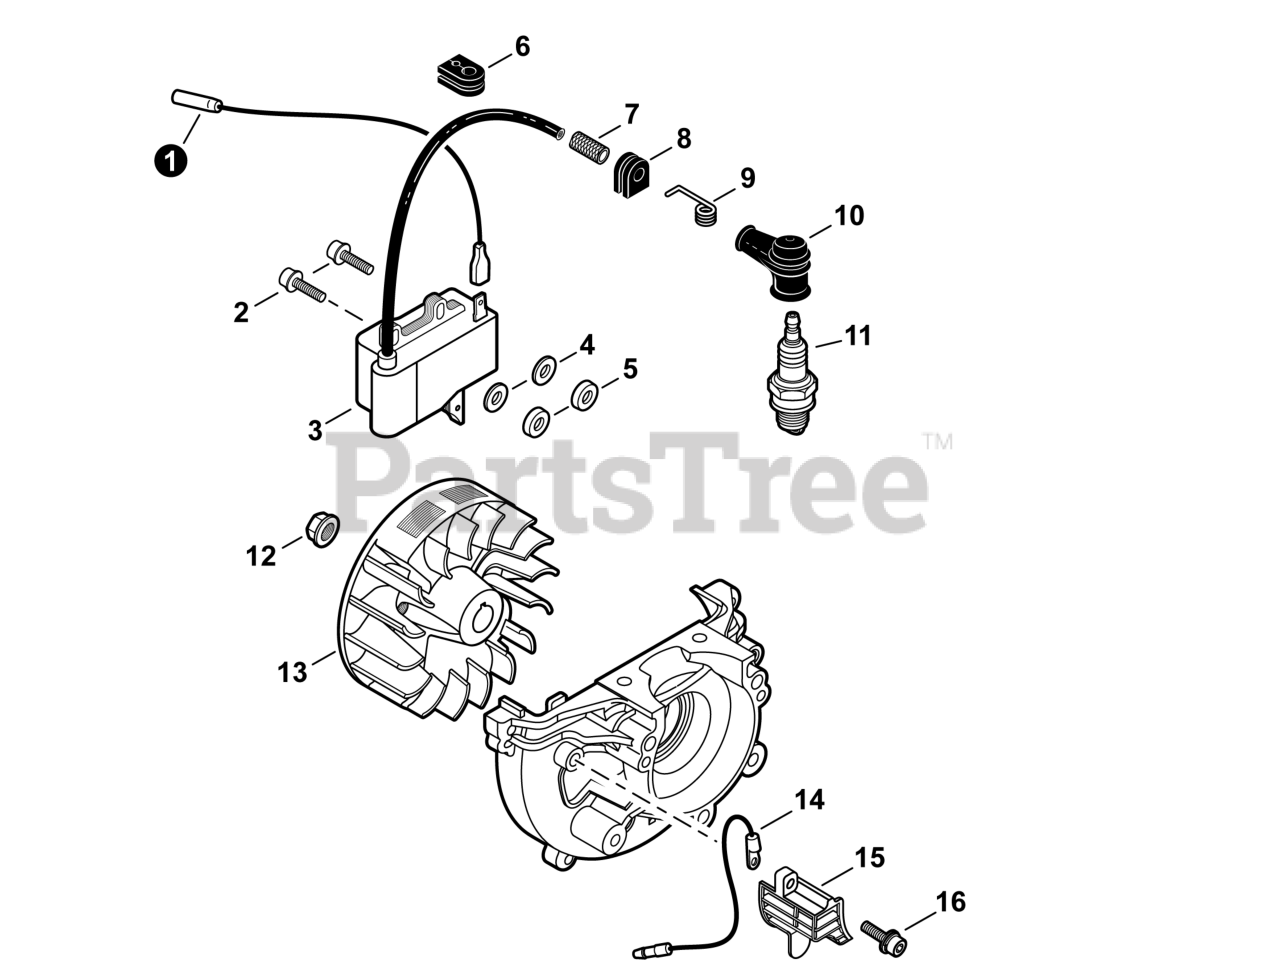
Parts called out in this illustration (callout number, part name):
1	LEAD - IGNITION
3	COIL, IGNITION
4	WASHER 4 MM
5	INSULATOR 4
6	GROMMET
7	TUBE, INSULATOR
9	TERMINAL, SPARK PLUG
10	CAP, SPARK PLUG
11	SPARK PLUG - BPM8Y
12	NUT, FLANGE M8
13	FLYWHEEL
14	LEAD - GROUND
15	COVER, DUST
16	BOLT 5x16
